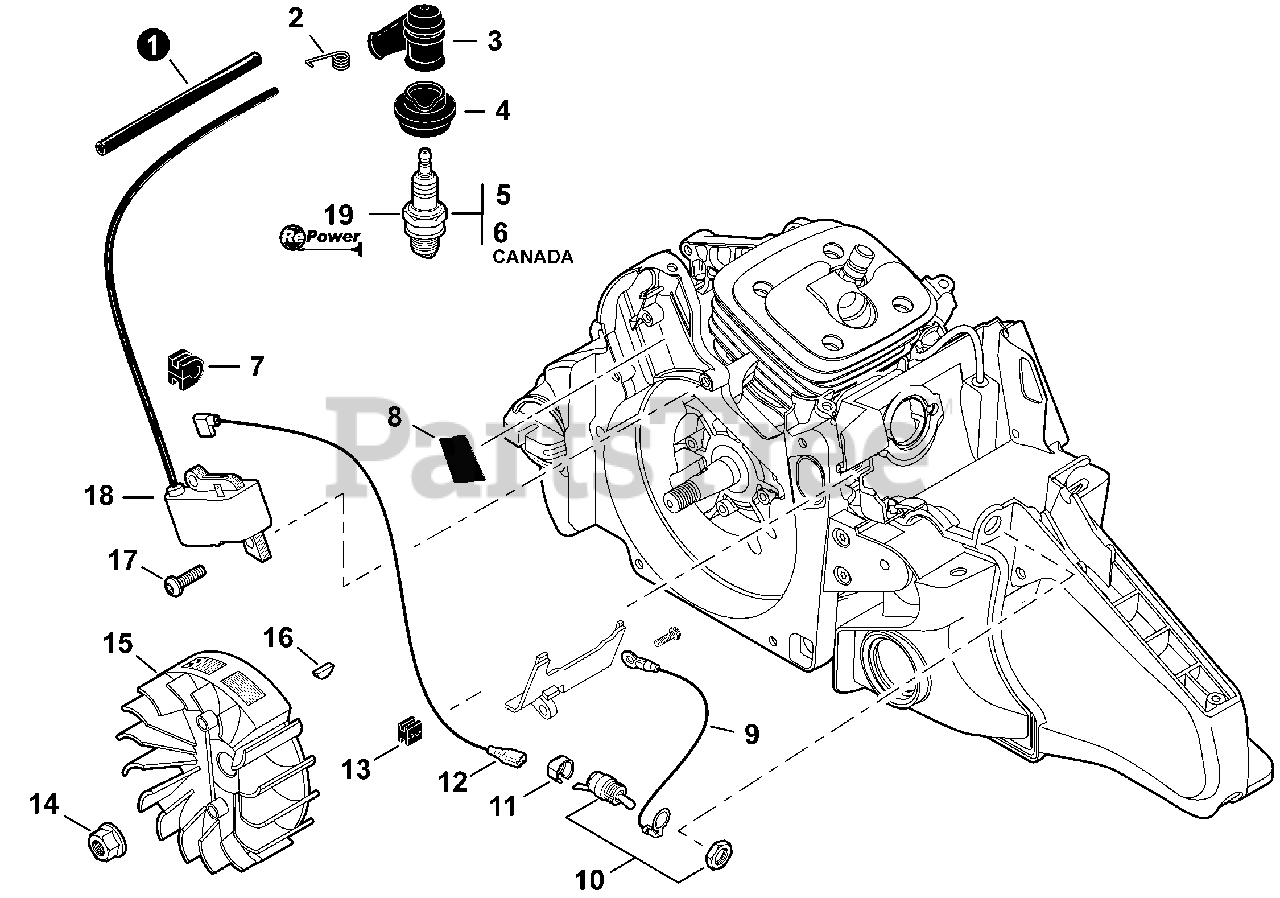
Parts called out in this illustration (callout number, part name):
1	TUBE, IGNITION COIL 6×7.2×70
2	TERMINAL, SPARK PLUG
3	CAP, SPARK PLUG
4	SEAL, SPARK PLUG
5	SPARK PLUG - BPM8Y
6	SPARK PLUG - BPMR8Y
8	CUSHION
9	LEAD - GROUND L= 170
10	SWITCH, ON-OFF
11	CAP, SWITCH
12	LEAD - IGNITION L= 280
13	GROMMET, LEAD
14	NUT, FLANGE M8
15	FLYWHEEL
16	KEY, WOODRUFF
17	BOLT, TORX 5×16
18	COIL, IGNITION
19	TUNE-UP KIT - REPOWER
